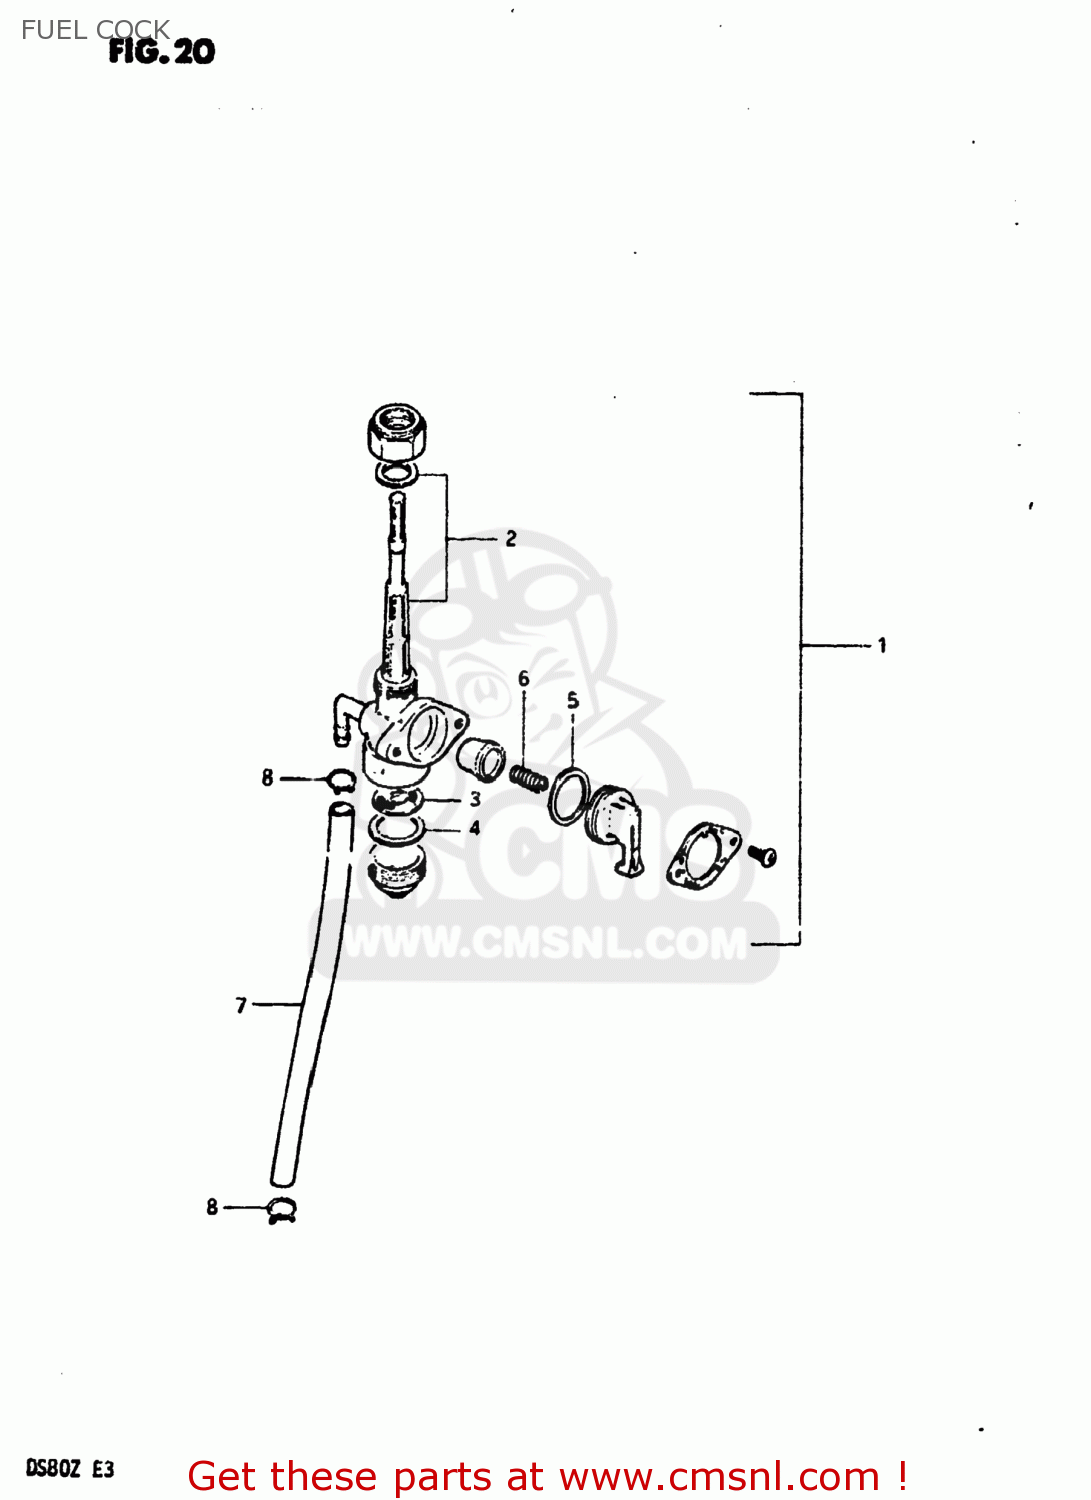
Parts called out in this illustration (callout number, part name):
1	COCK ASSY,FUEL
2	FILTER SET,FUEL
3	NET,STRAINER
4	GASKET,STRAINER CUP (NAS)
5	GASKET
6	SPRING,FUEL COCK VALUE
7	HOSE
8	CLAMP
